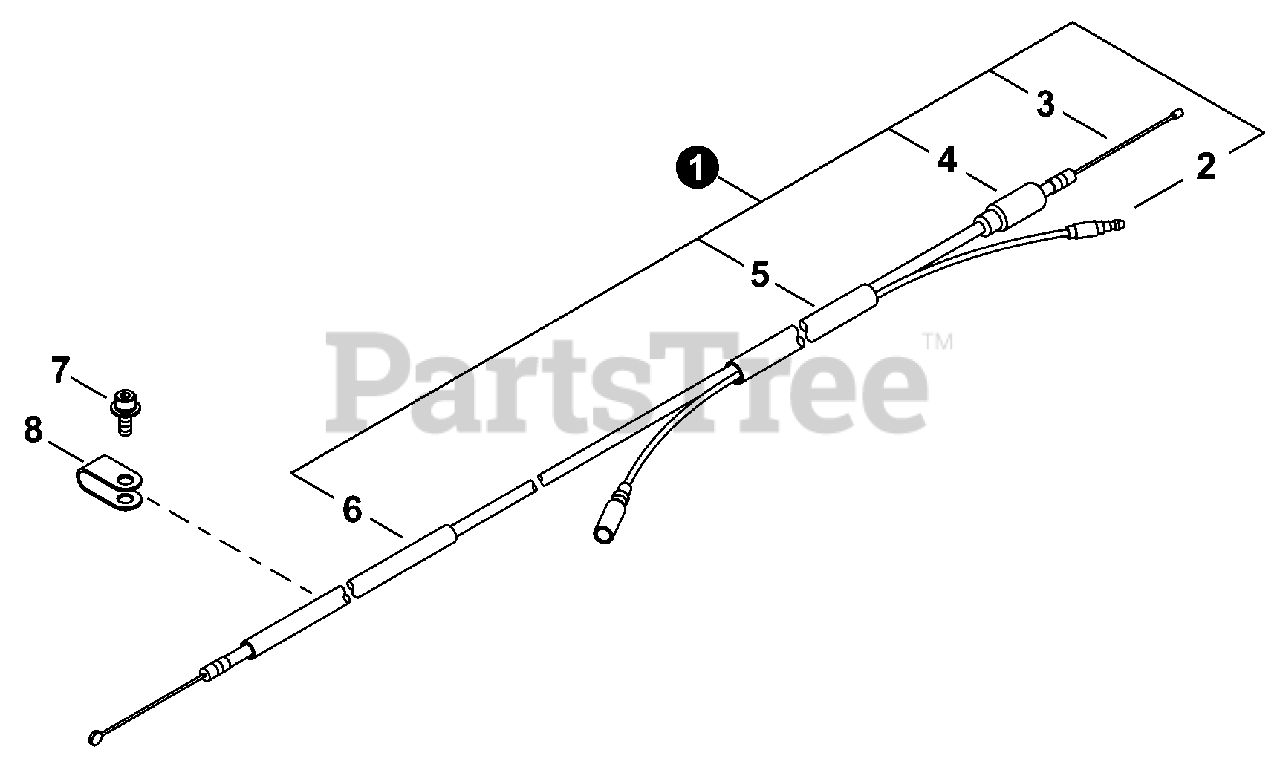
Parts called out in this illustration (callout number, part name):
1	CABLE ASSY, THROTTLE
2	LEAD - GROUND
3	CABLE, THROTTLE
4	CAP, CARBURETOR
5	TUBE, PROTECTIVE
6	TUBE, THROTTLE CABLE
7	BOLT M4×12
8	CLAMP
